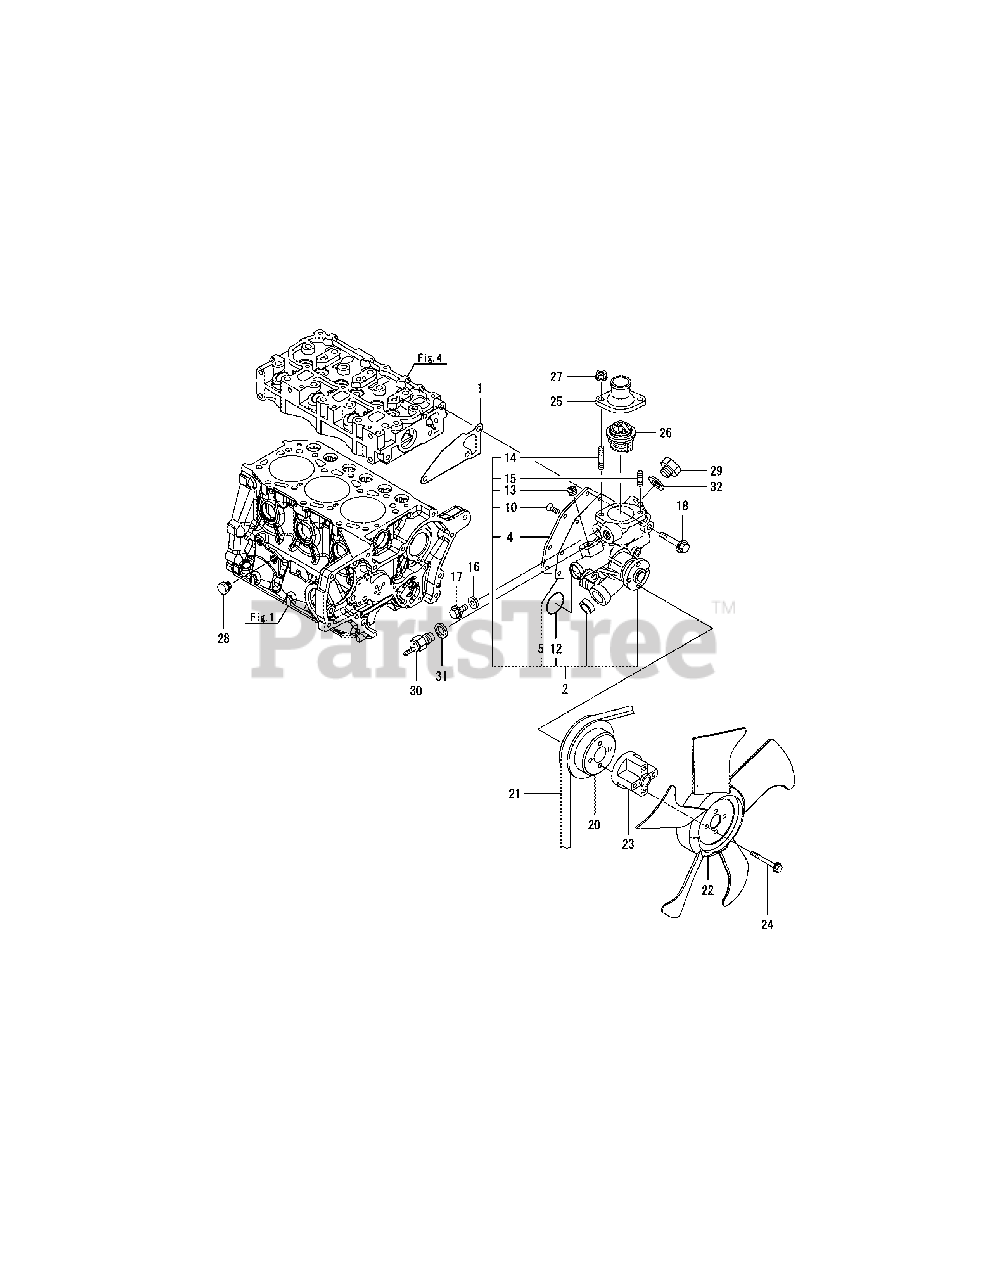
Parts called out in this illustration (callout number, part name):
1	GASKET, WATER PUMP
2	PUMP ASSY, WATER
4	COVER, WATER PUMP
5	GASKET, WATER PUMP
15	STUD M 8X 20 PLATED
16	GASKET 8, ROUND
17	BOLT M 8X 12 PLATED
18	BOLT M 8X 45 PLATED
20	V-PULLEY, WATER PUMP
24	BOLT M 6X 55 PLATED
25	COVER, THERMOSTAT
30	SWITCH, THERMOSTAT
